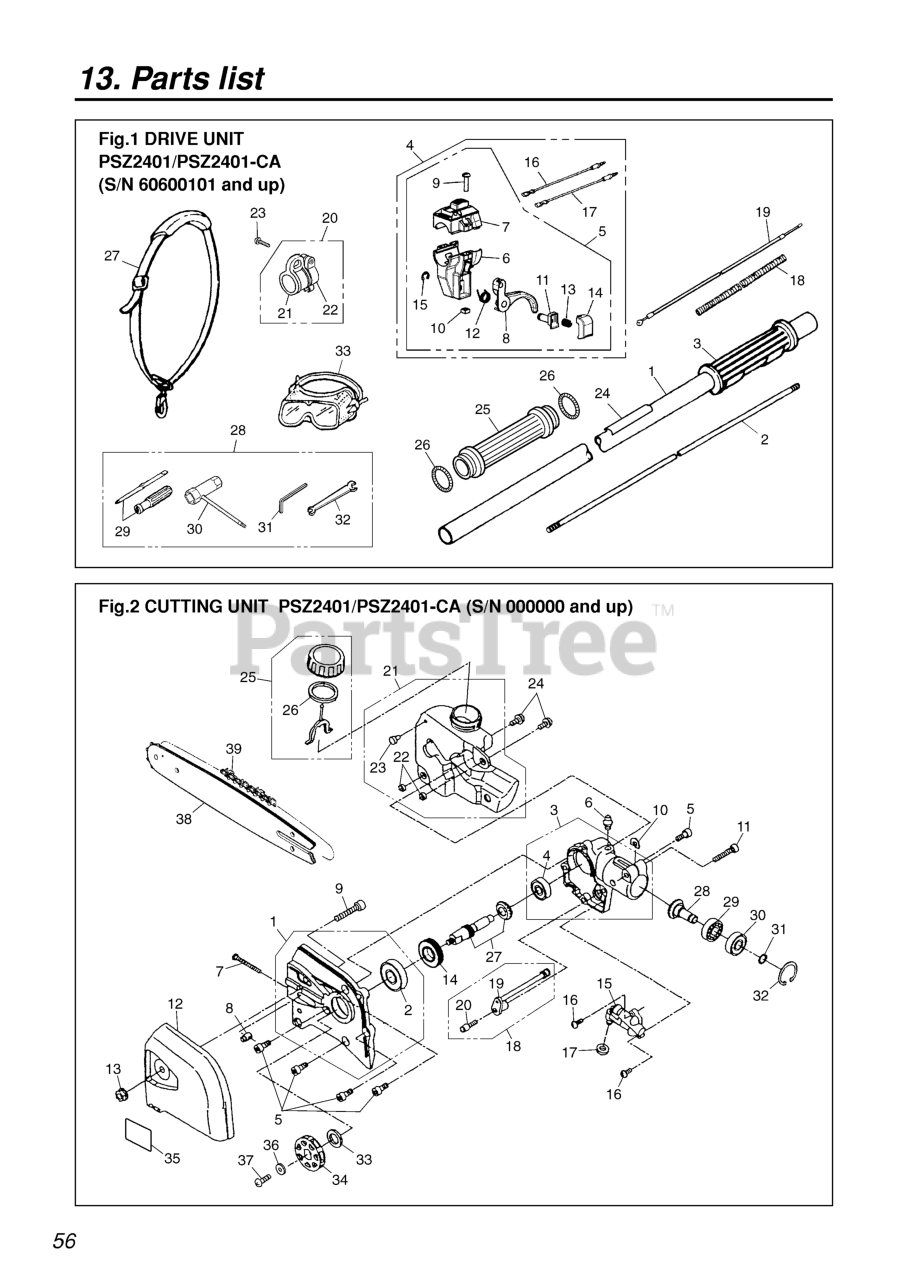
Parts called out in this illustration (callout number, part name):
1	PIPE COMP.
2	SHAFT
3	GRIP
4	LEVER ASSY
5	LEVER ASSY
7	COVER
8	LEVER
16	CORD (A), BLACK
17	CORD (B), RED
18	TUBE
19	CABLE COMP
20	HANGER ASSY
23	SCREW
24	NAME PLATE
25	GRIP
26	SPRING
27	STRAP ASSY.
28	TOOL-SET
29	DRIVER
32	SPANNER
33	GOGGLE
A1	GEAR CASE COMP-L
A2	BEARING
A3	GEAR CASE COMP-R
A5	BOLT
A6	FITTING, GREASE
A7	SCREW
A8	NUT
A9	BOLT
A10	SIM
A12	CHAIN COVER
A13	NUT
A14	WORM GEAR
A15	OIL PUMP ASSY
A17	GASKET
A18	OIL PIPE ASSY
A19	OIL PIPE
A20	FILTER
A21	OIL TANK ASSY
A22	COLLAR
A23	VALVE
A24	SCREW
A25	OIL CAP ASSY
A26	GASKET, OIL CAP
A27	GEAR SHAFT
A28	BEVEL, PINION
A29	BEARING
A31	SNAP RING
A32	SNAP RING
A33	COLLAR
A34	SPROCKET
A35	LABEL
A36	WASHER
A37	SCREW
A38	12
A39	12
